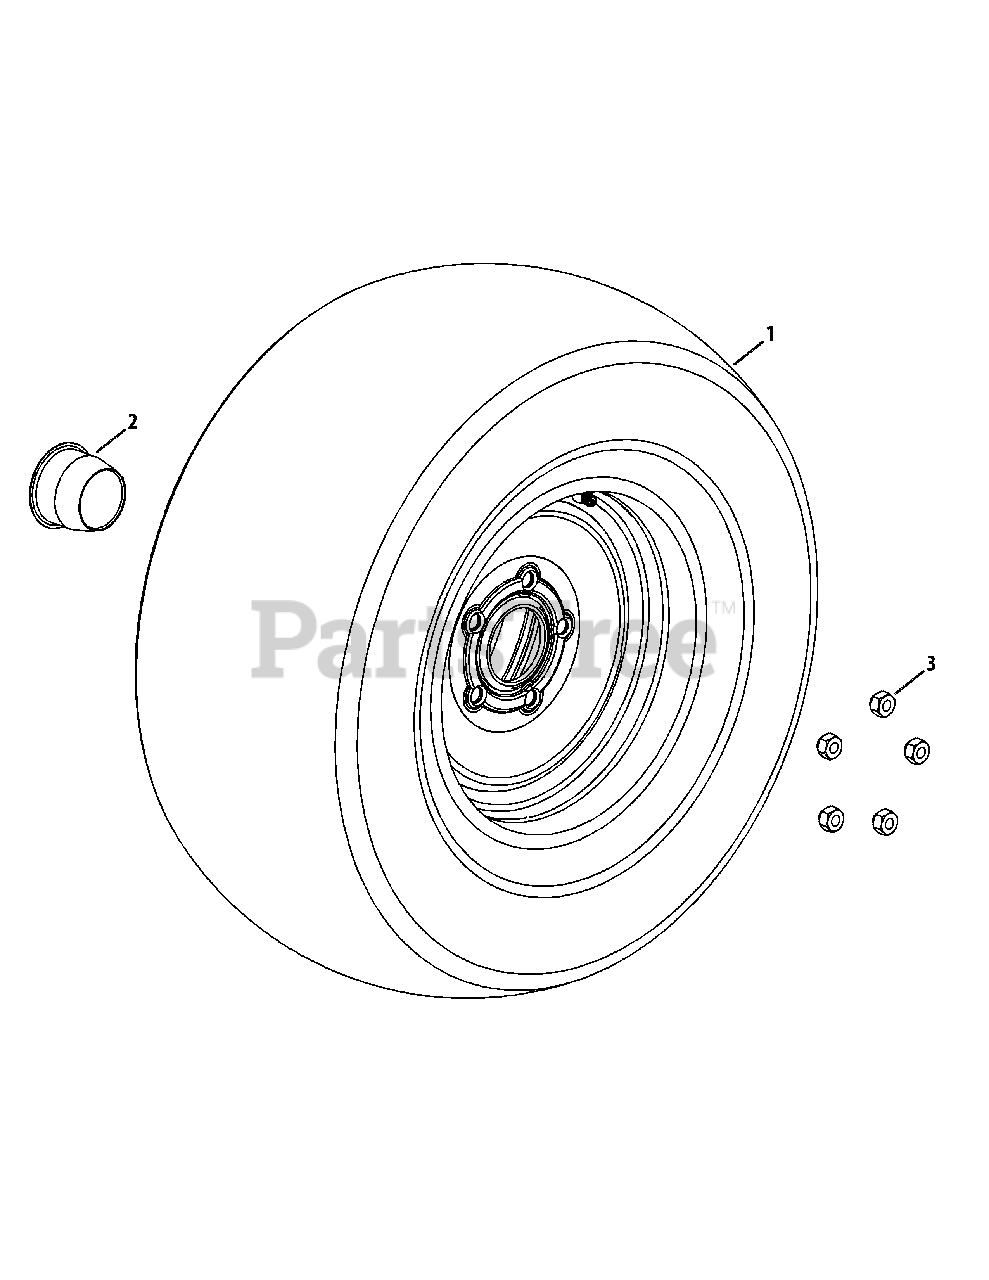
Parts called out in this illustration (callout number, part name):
1	Whl Asm, Compl, 25 x 10-12, Turf
1	Rim Asm, 12 x 7
1	Tire, 24 x 10-12, Turf
3	Nut, Lug, 7/16-14
